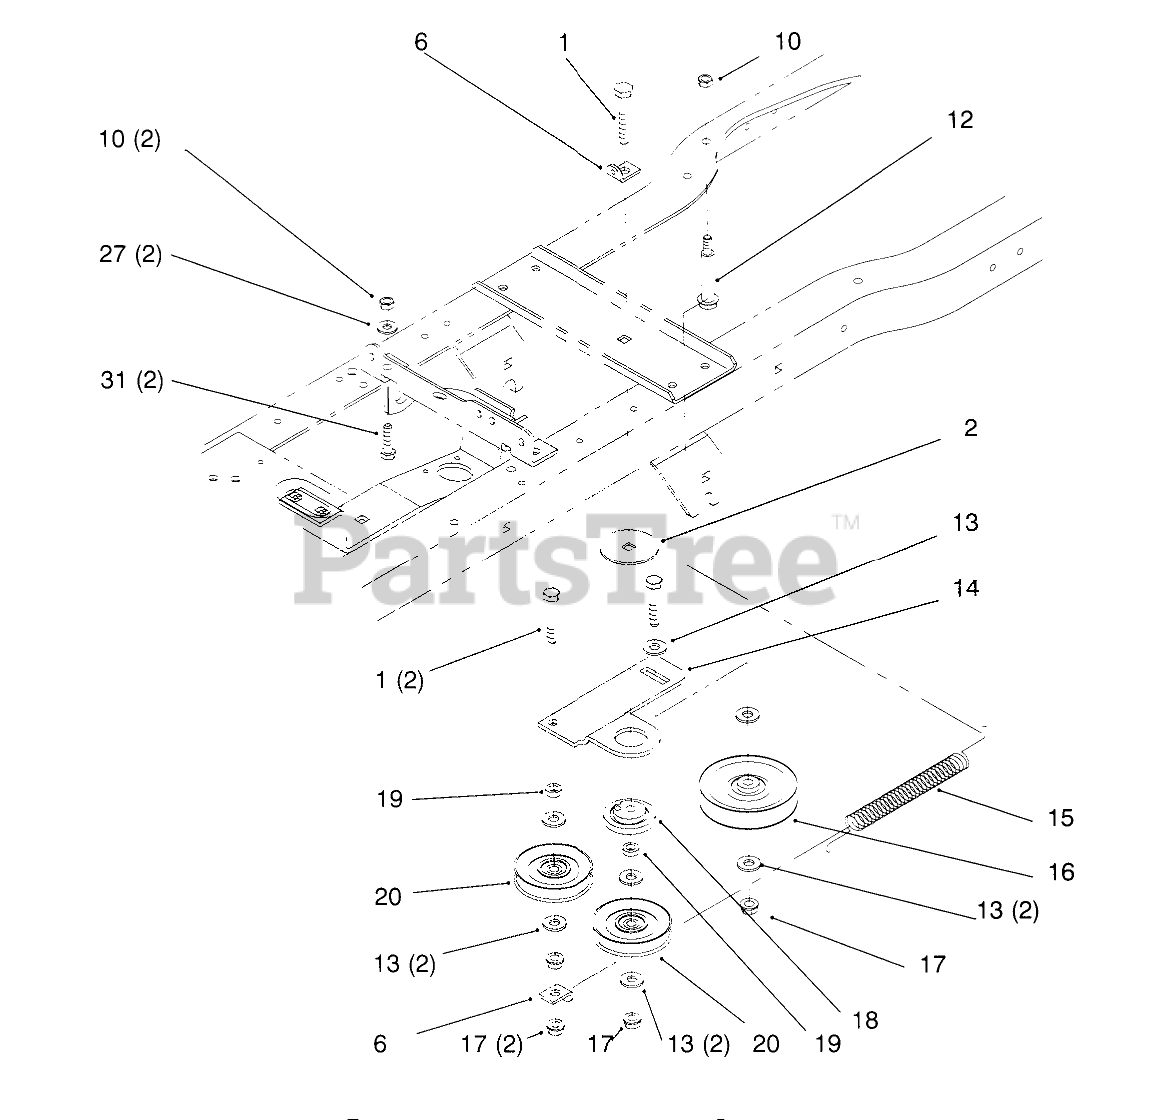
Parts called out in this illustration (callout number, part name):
1	Screw-HH (Only On: 72043,72063,72103)
2	Washer-Bearing (Only On: 72043,72063,72103)
6	Clip-Spring (Only On: 72043,72063,72103)
10	Nut-Lock (Only On: 72043,72063,72103)
12	Bolt-Shoulder (Only On: 72043,72063,72103)
13	Washer-Flat (Only On: 72043,72063,72103)
14	Arm-ldler (Only On: 72043,72063,72103)
15	Spring-Extension (Only On: 72043,72063,72103)
16	Pulley-Flat (Only On: 72043,72063,72103)
17	Nut-Lock (Only On: 72043,72063,72103)
18	Bushing (Only On: 72043,72063,72103)
19	Spacer (Only On: 72043,72063,72103)
20	Pulley-Idler (Only On: 72043,72063,72103)
27	Washer-Flat (Only On: 72043,72063,72103)
31	Screw-HH (Only On: 72043.72063.721035
